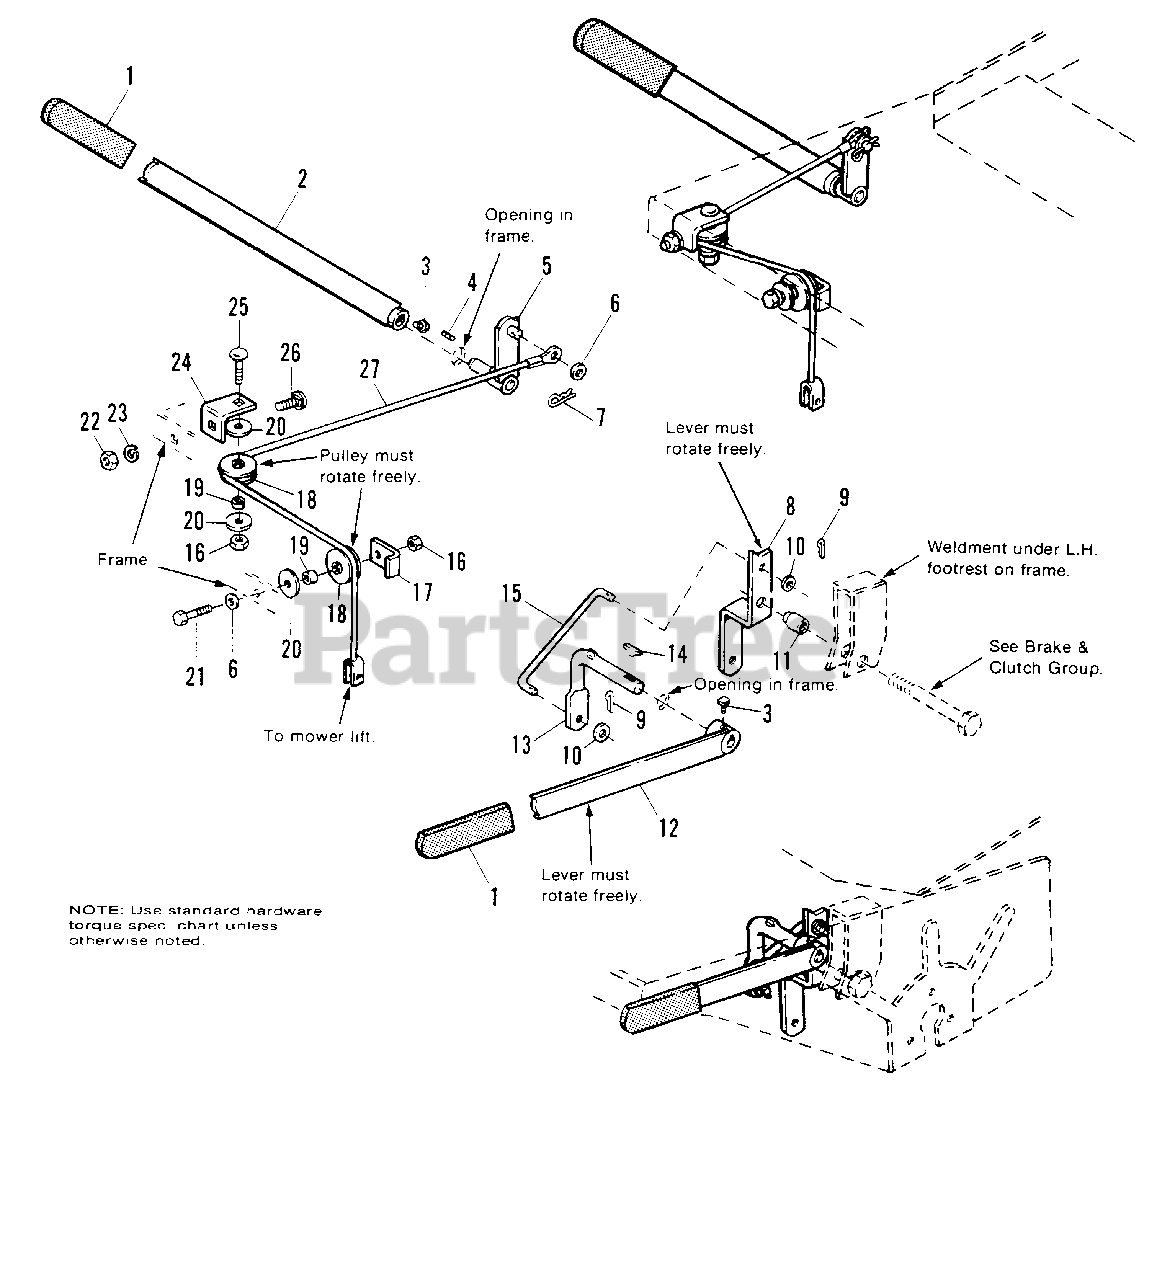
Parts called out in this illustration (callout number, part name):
1	GRIP
2	LEVER ASSY., Lift
3	SET SCREW, 1/4-20 x 3/8
4	KEY, 3/16 x 5/8
5	LEVER ASSY.
6	WASHER, 1/4
7	PIN, Quick
8	LEVER, PTO
9	PIN, Cotter, 3/4
10	WASHER, 5/16
12	LEVER ASSY., PTO
13	LEVER, PTO
14	KEY, Hi-Pro, 5/32 x 5/8
16	NUT, Hex, Lock, 1/4-20
17	GUIDE, Cable
18	PULLEY, Lift Cable
19	SPACER
20	WASHER, 1/4
21	CAPSCREW, 1/4-20 x 1.0
22	NUT, Hex, 5/16-18
23	LOCKWASHER, 5/16
24	BRACKET, Pulley
25	CARRIAGE BOLT, 1/4-20 x 1-1/4
26	CARRIAGE BOLT, 5/16-18 x 3/4
27	CABLE ASSY., Lift
